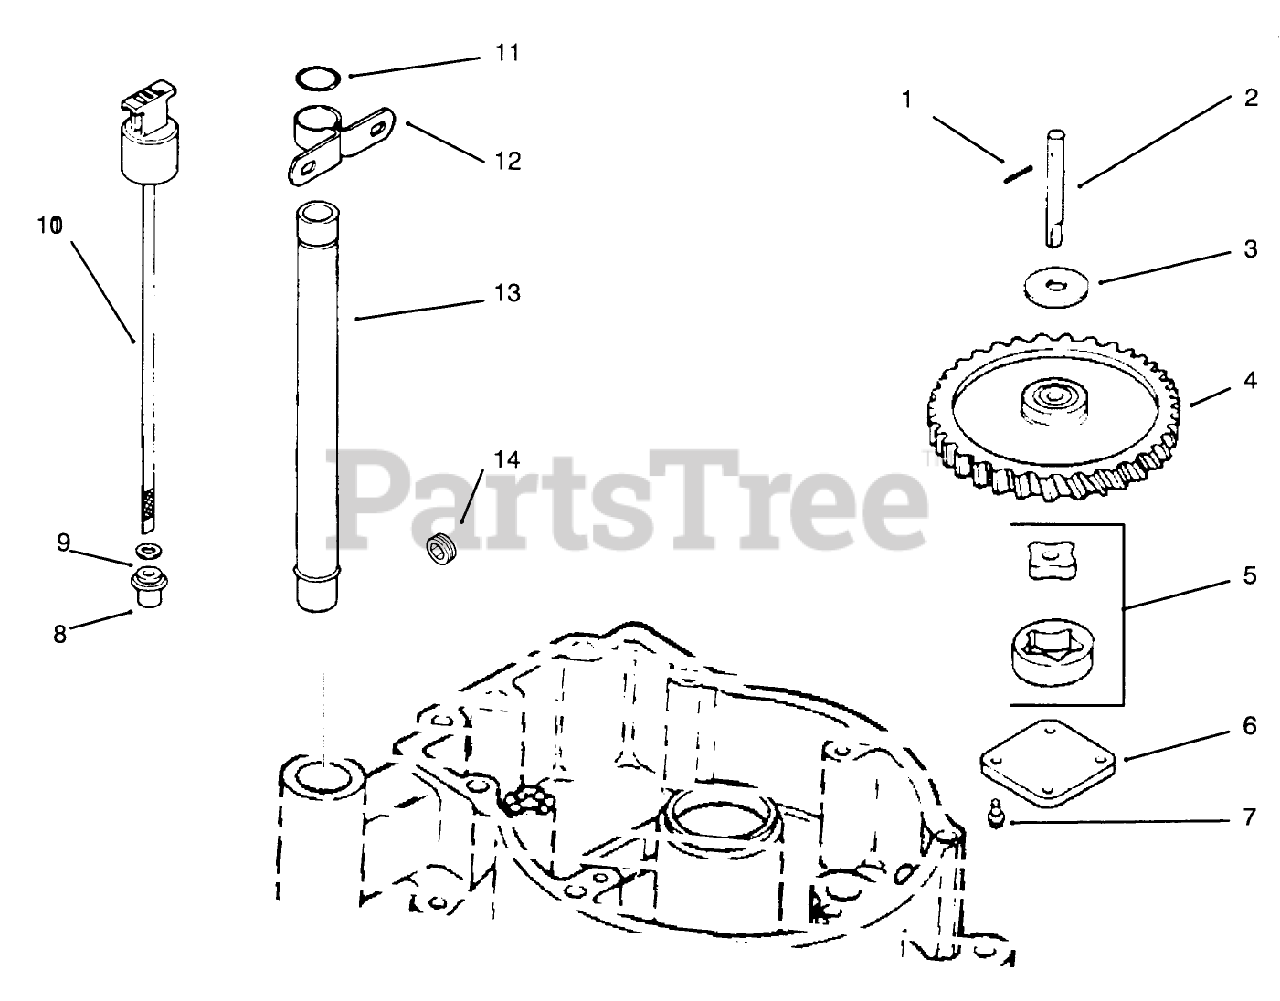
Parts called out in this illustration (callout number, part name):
1	Pin-Roll
2	Shaft-0il Pump
3	Spacer-Shim
4	Gear-0il Pump
5	Rotor Set
6	Cover-Oil Pump
7	Screw
8	Seal-Rubber
9	Screw
10	Dipstick
12	Bracket-Oil tube
13	Tube-Oil Fill
14	Plug, Cup
